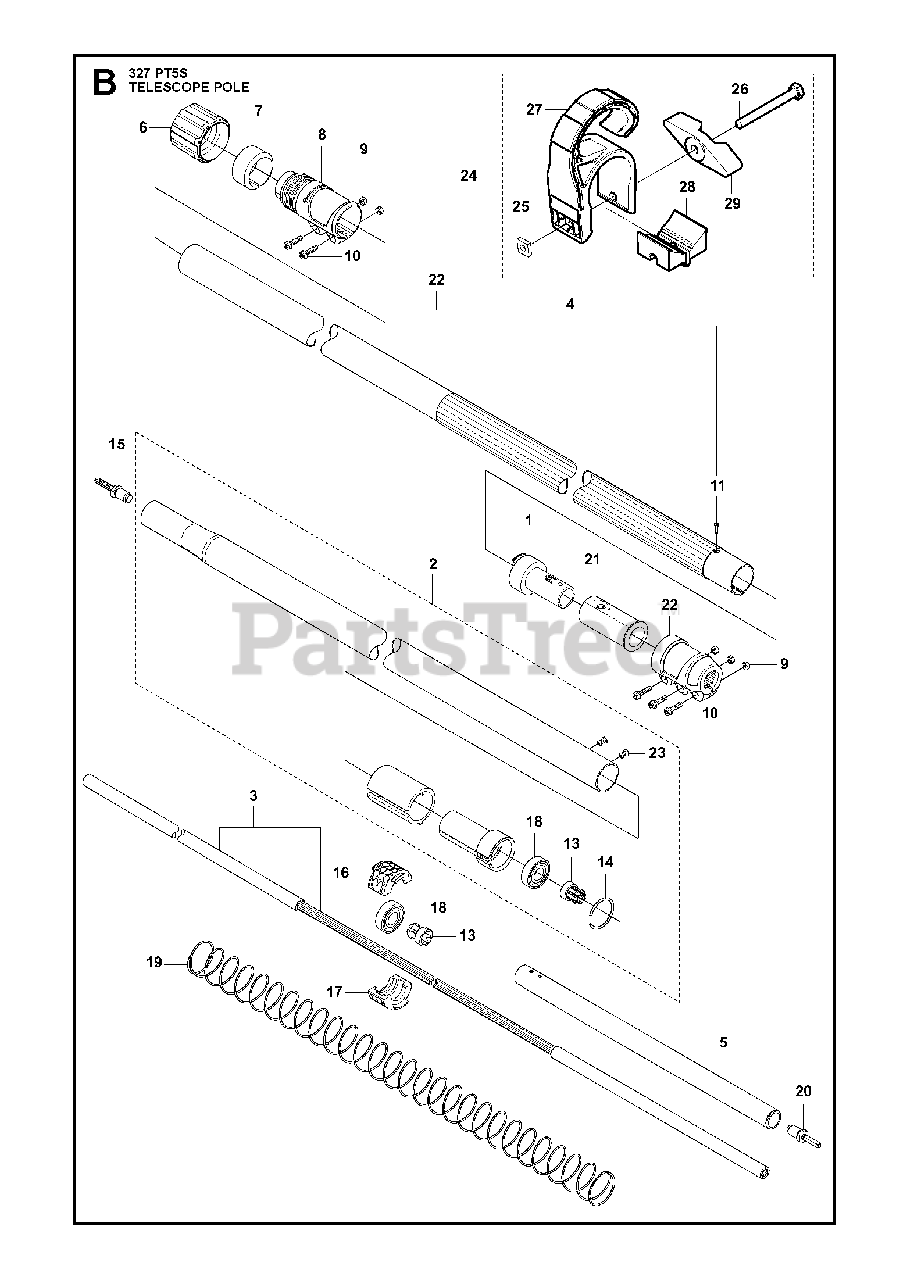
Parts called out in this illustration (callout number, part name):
1	BEARING SLEEVE
3	DRIVE SHAFT ASSY
4	FRAME TUBE
5	TUBE FOR MODEL 327PT5S
8	CLAMPING SLEEVE
11	SCREW
13	SLIDING SHOE
14	RETAINING RING SGH 28
15	ADAPTER
16	BEARING HOUSING
17	BEARING HOUSING
18	BALL BEARING
21	GUIDE BUSHING
22	CLAMPING SLEEVE
23	RIVET
25	NUT
26	SCREW M6X55
28	SPACING BLOCK
29	HANDLE
